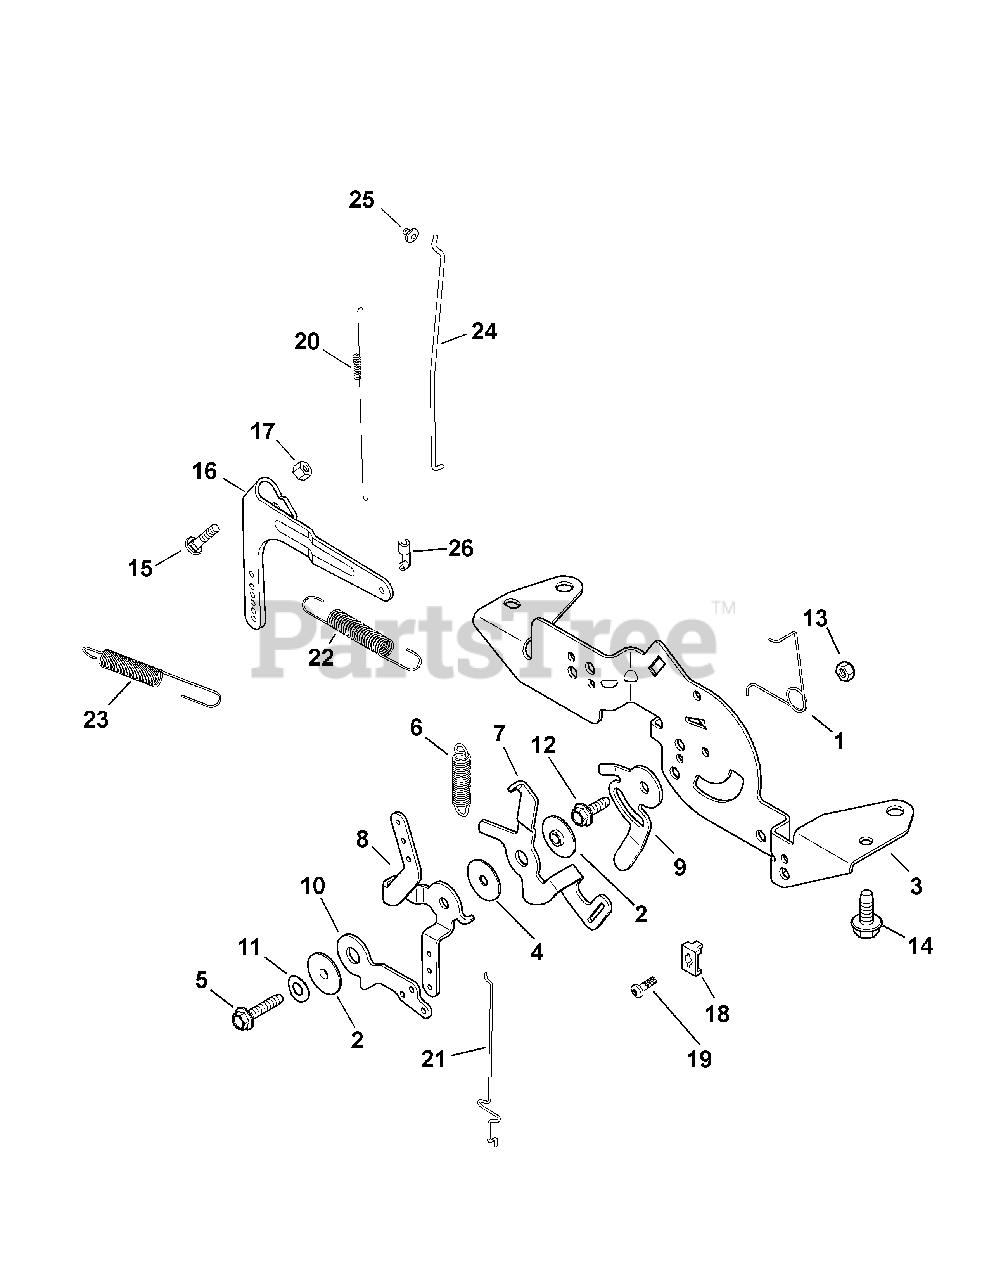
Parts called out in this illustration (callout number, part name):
1	Choke Return Spring
3	Control Bracket
4	Flat Washer, 5.5mm
5	Screw, M5 x 0.8 x 25mm
6	Speed Control Spring
7	Governor Spring Lever
8	Speed Control Lever
9	Speed Setting Lever
10	Choke Lever
11	Spring Washer, 1/4
12	Flange Screw, M5 x .8 x 16
13	Lock Nut, M5 x 8
14	Flange Screw, M6 x 1.0 x 16
15	Bolt, M6 x 1.0 x 25
16	Governor Lever
17	Flange Nut, M6 x 1.0
18	Cable Clamp
19	Screw, M5 x .8 x 16
20	Linkage Spring
21	Choke Linkage
22	Governor Spring
23	Governor Spring
24	Throttle Linkage
25	Linkage Retaining Bushing
26	Throttle Linkage Bushing
